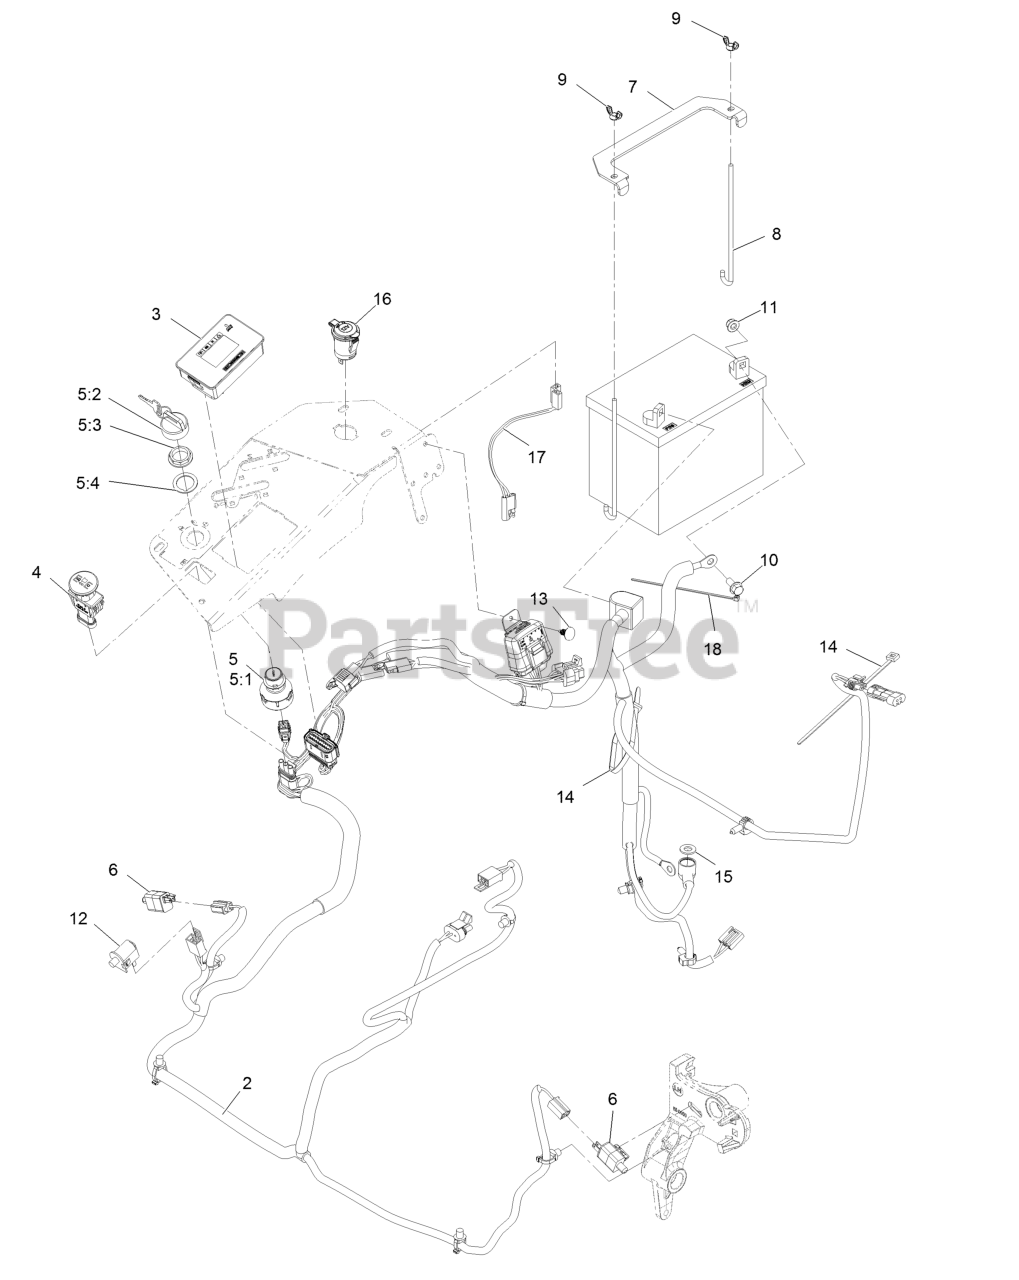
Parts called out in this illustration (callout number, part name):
2	Wire Harness ASM
3	Meter-Hour
4	Switch-PTO, Sealed
5	Ignition Switch ASM
5:1	Switch-Ignition
5:2	Nut-Mounting
5:3	Ignition Key Set
5:4	Washer-Backup
7	Strap-Tie Down, Battery
8	Bolt-Holddown
9	Wingnut-Nyloc 1/4-20
10	Screw-HH Flg 5/16-18 X 3/4
11	Nut-Nyloc 5/16-18 Flg
13	Plug-Plastic
14	Tie-Cable 7 15/16 (Large)
15	Washer-3/8 SAE
16	Port-Power, 12V
17	Harness-Receptacle, 12V
18	Tie-Cable 5 1/2 (Small)
